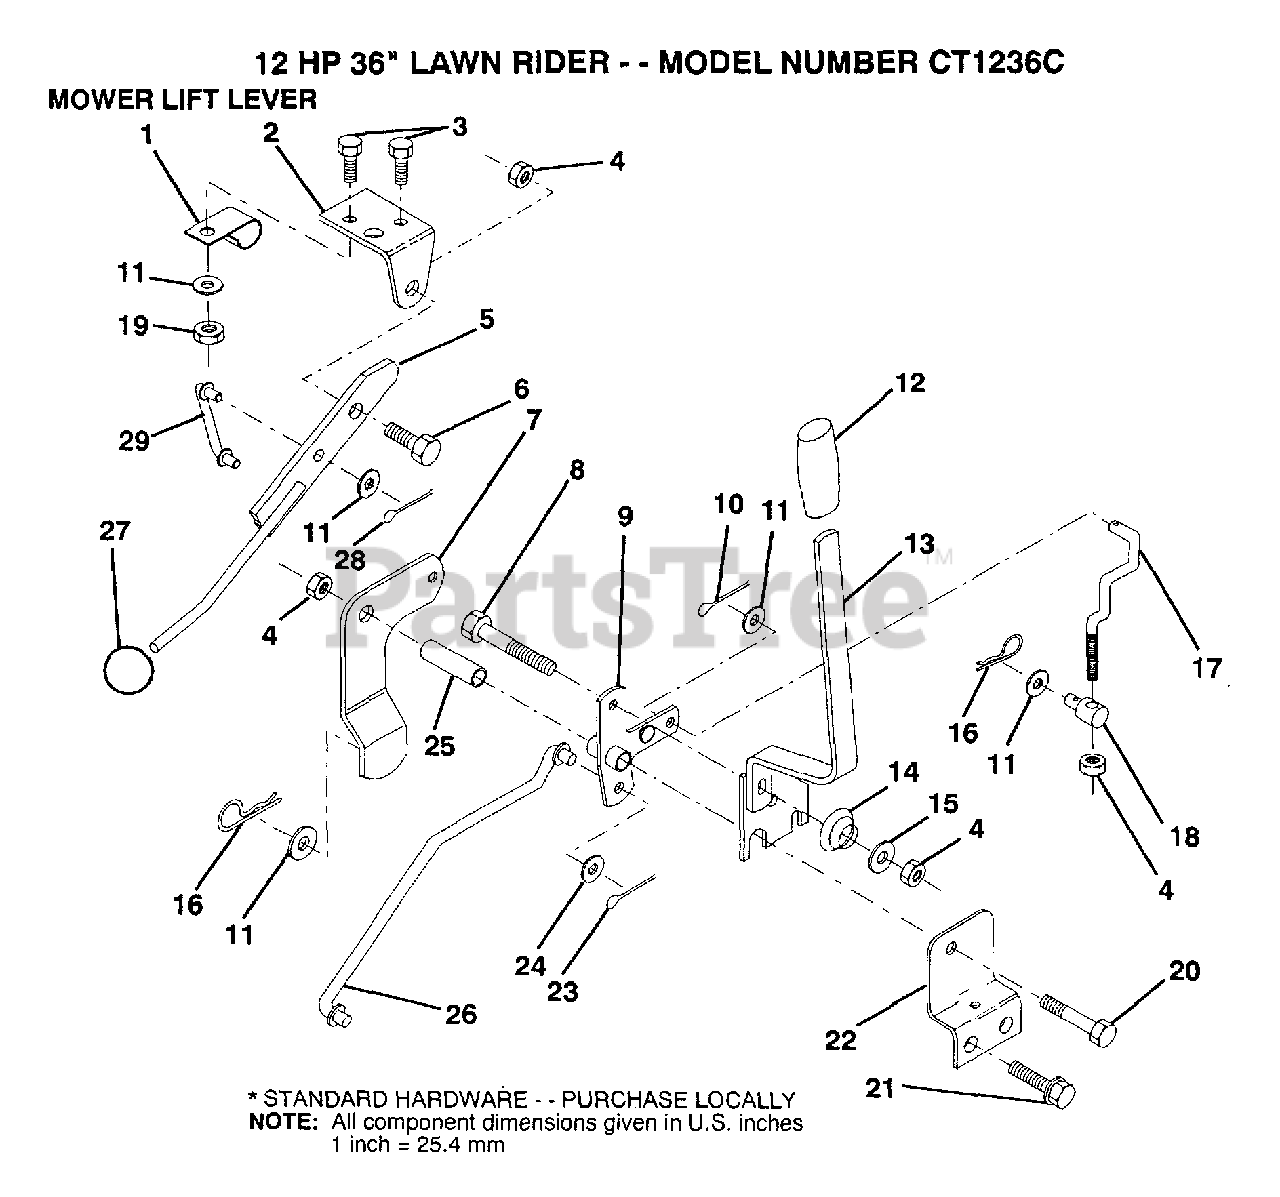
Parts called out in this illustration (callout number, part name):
1	"CLIP,INSULATOR"
2	BRKT CLUTCH
3	BOLT
5	CLUTCH LEVER AS
6	"BOLT, SHOULDER LT"
7	CLUTCH ARM ASS'Y
8	BOLT
9	"BELLCRANK,LIFT"
10	COTTER PIN
11	WASHER
12	GRIP HANDLE
13	"HDLE,LIFT T"
14	SPRING COMPRESSIO
15	WASHER T
16	SPRING.RETAINER
17	"LINK,LIFT FRT"
18	TRUNION
20	BOLT
21	SCREW LT
22	"BRKT,MOWER HGT"
23	PIN COTTER 1/8
25	TUBE SPACER
26	"ROD,MOWER LIFT "
27	KNOB
29	"LINK,MOWER LIFT"
